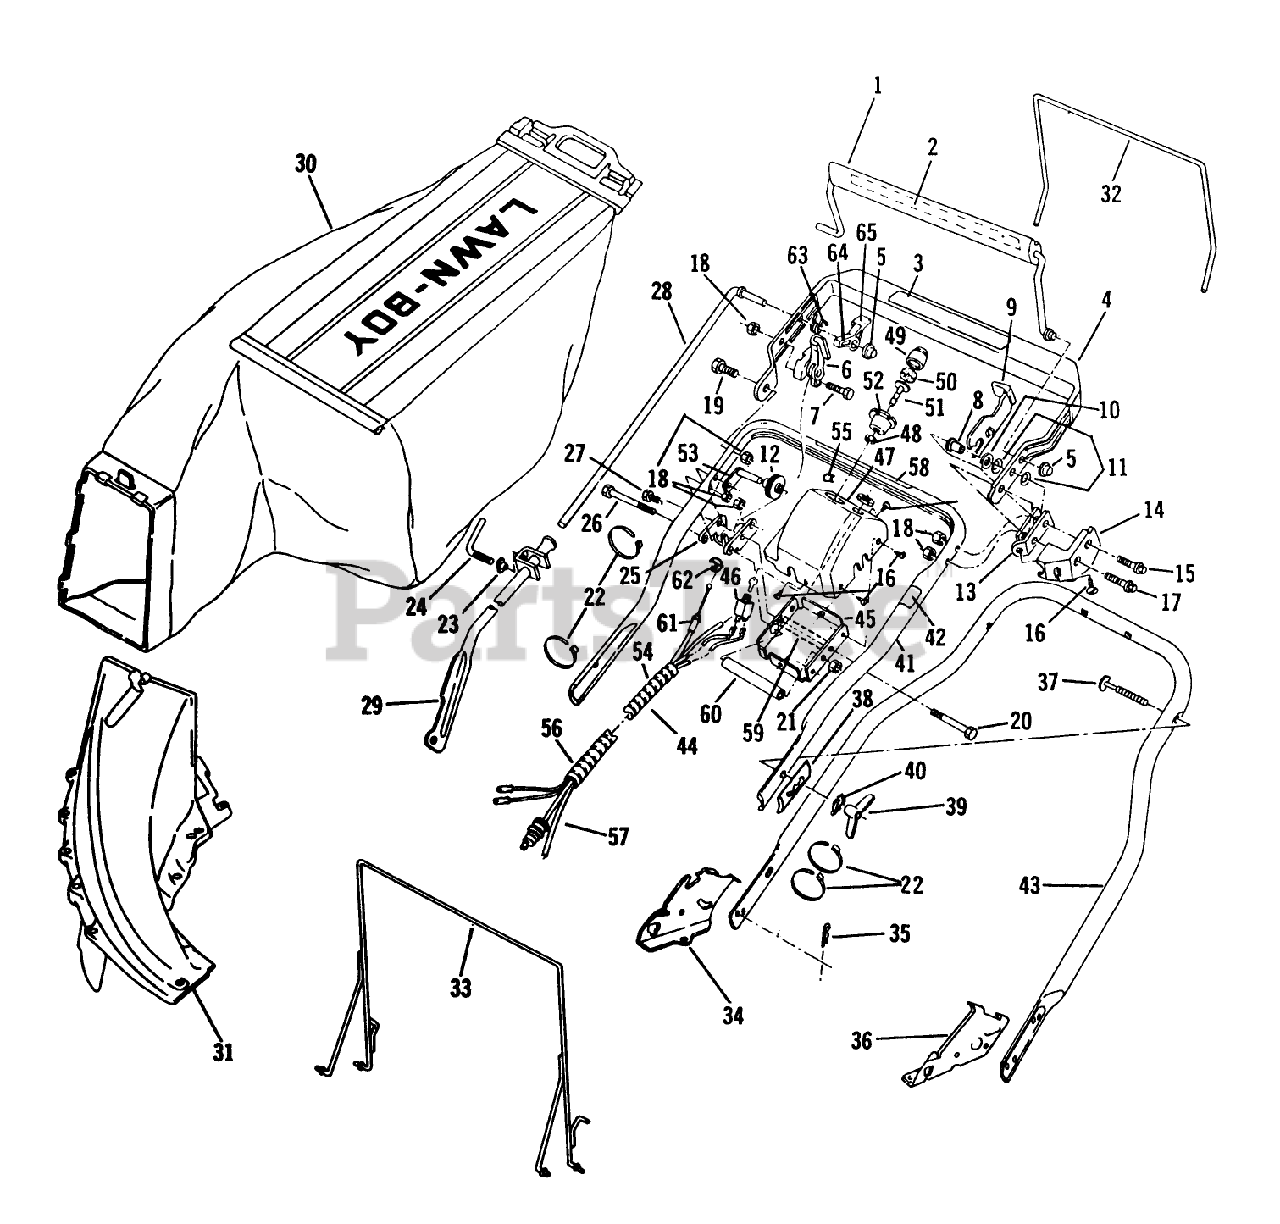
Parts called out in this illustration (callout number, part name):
8	SPACER
10	WASHER M
13	DOWN STOP
14	LOCKOUT GUARD
15	BOLT SHOU
16	SCREW F
17	SCREW
18	LOCKNUT E
19	BOLT
26	BOLT-CONSOLE
32	HANGER
33	HANGER AY
34	BRACKET ASM - HANDLE, SP, RH
35	HAIR PIN
36	BRACKET ASM - HANDLE, SP, LH
37	BOLT QUALITY
38	BRACKET R/B 613462
39	NUT-WING
40	WASHER-CURVED
46	SWITCH AY
48	LOCKNUT S
50	FILTER S
59	SPACER
61	CONTROL CABLE
62	RET. RING
